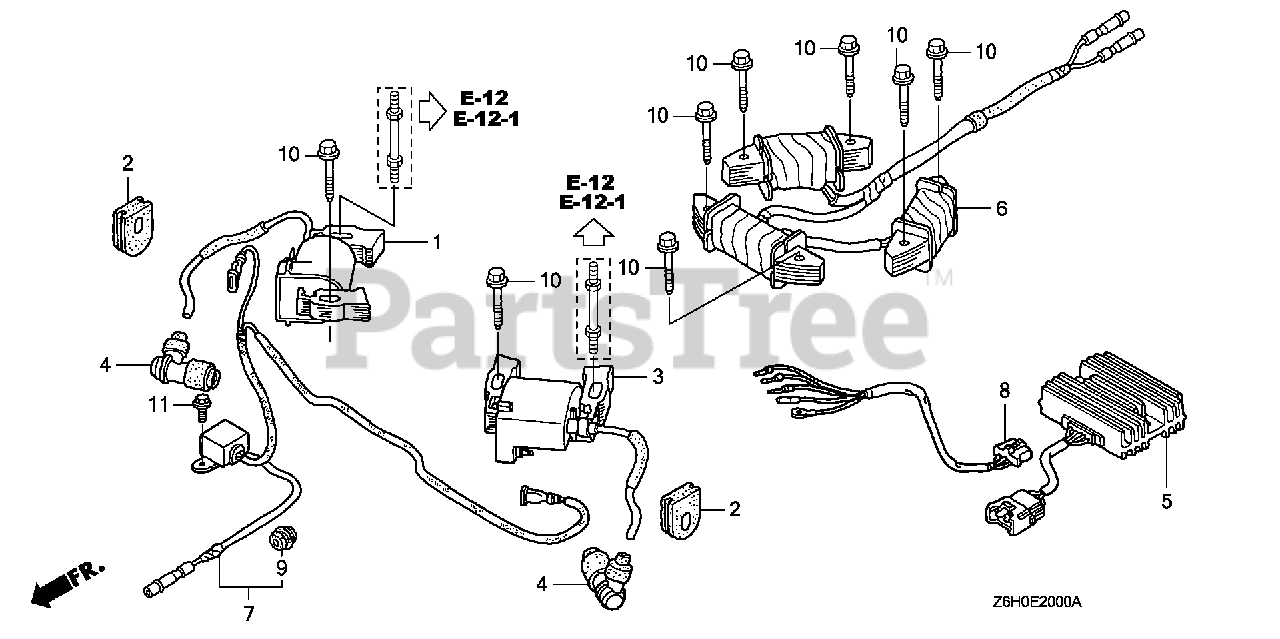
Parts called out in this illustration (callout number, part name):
1	COIL ASSY., IGNITION
2	GROMMET, IGNITION WIRE
3	COIL ASSY., IGNITION
4	CAP ASSY., NOISE SUPPRESSOR
5	RECTIFIER ASSY., REGULATOR (20A)
6	COIL ASSY., CHARGE (12V/20A)
7	DIODE ASSY., ENGINE STOP
8	SUB-WIRE HARNESS ASSY.
9	GROMMET, TOOL
10	BOLT, FLANGE (6X32) (CT200)
11	BOLT, FLANGE (6X8)
